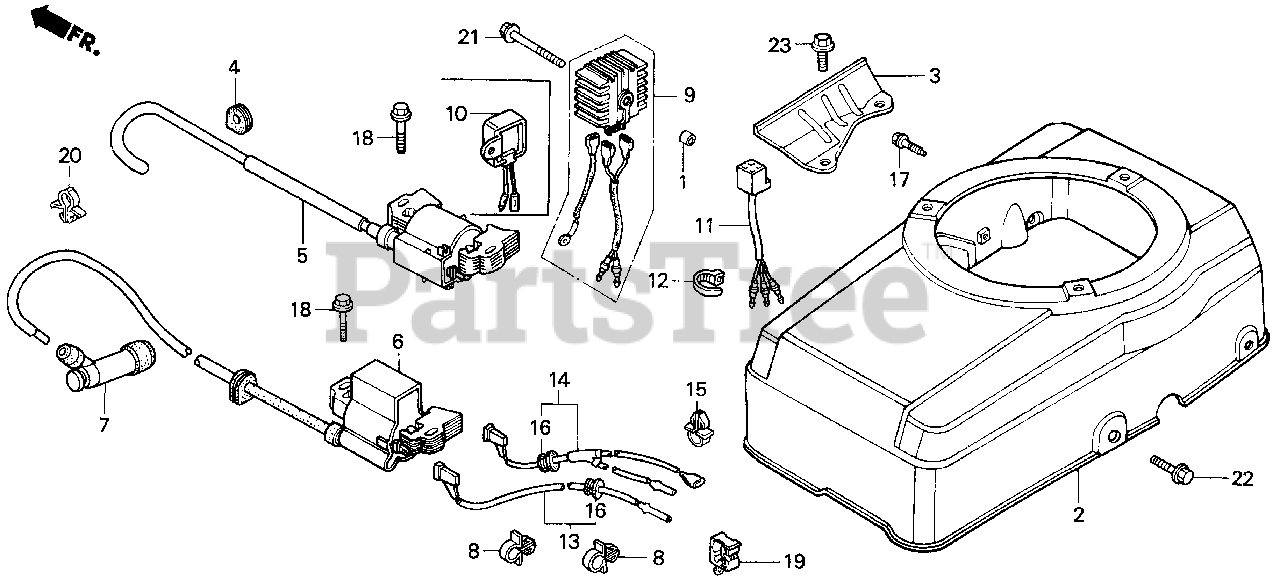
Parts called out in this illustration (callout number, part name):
1	SPACER, AIR CLEANER ELBOW
2	COVER, FAN *NH1* (Honda Code 4542924). (BLACK)
4	GROMMET, WIRE
5	COIL ASSY., IGNITION
7	CAP ASSY., NOISE SUPPRESSOR
8	CLIP, IGNITION WIRE (8MM)
9	RECTIFIER ASSY., SILICON
11	SUB-WIRE HARNESS ASSY. (AYP)
12	BAND B1, CABLE
13	WIRE, STOP SWITCH (AYP)
16	GROMMET, WIRE
17	BOLT, FLANGE (6X12) (CT200)
18	BOLT, FLANGE (6X28)
21	BOLT, FLANGE (6X40)
22	BOLT, FLANGE (8X16)
